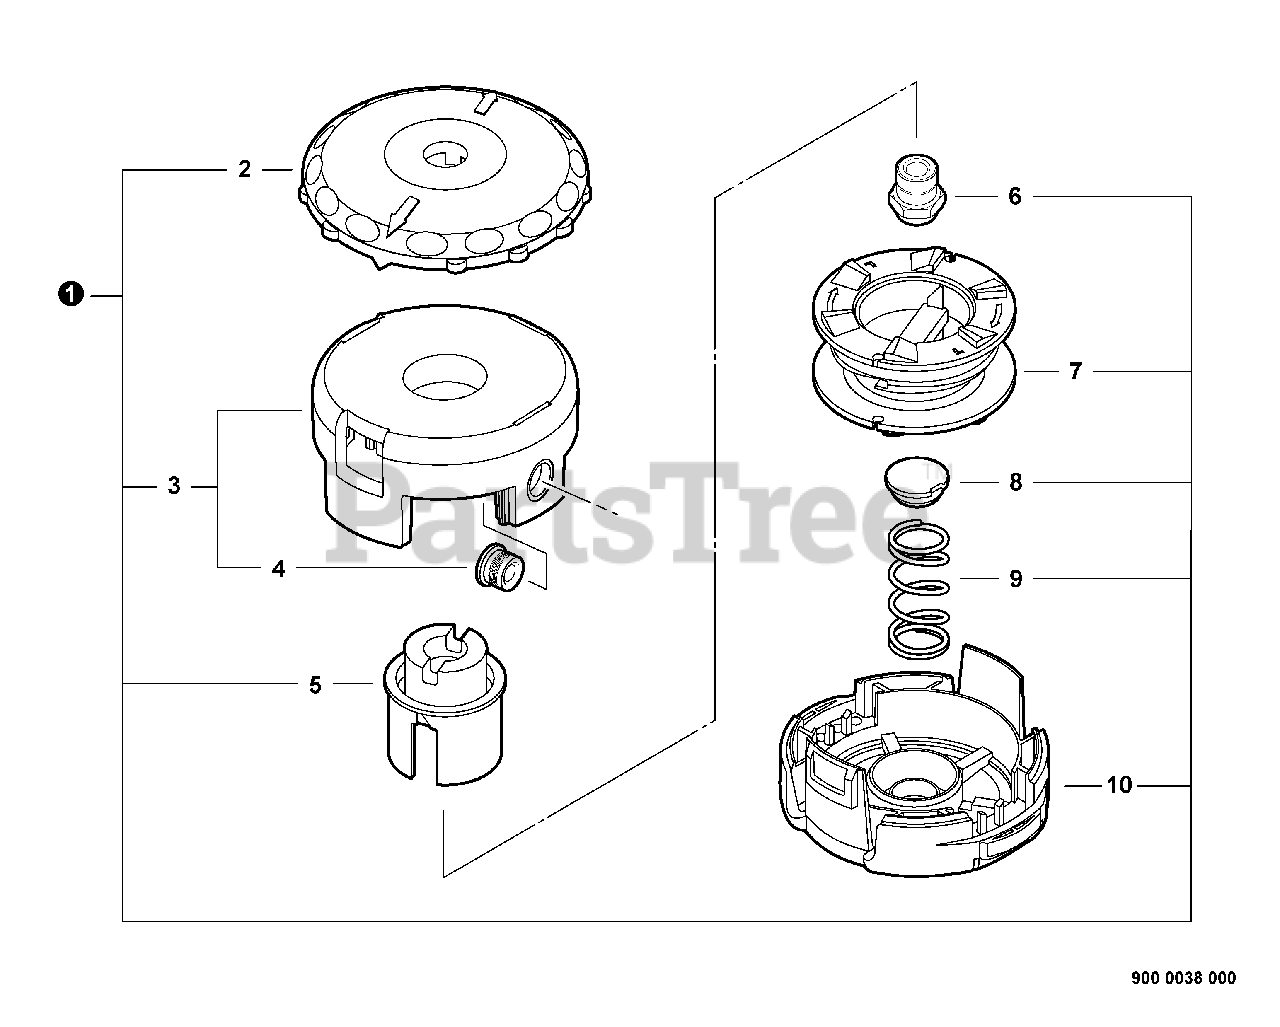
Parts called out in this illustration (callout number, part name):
1	SPEED-FEED 400 TRIMMER HEAD
3	SPOOL COVER ASSY
5	HUB - BLACK -- LEFT HAND
6	ARBOR - GOLD -- LEFT HAND
8	RETAINER, SPRING
